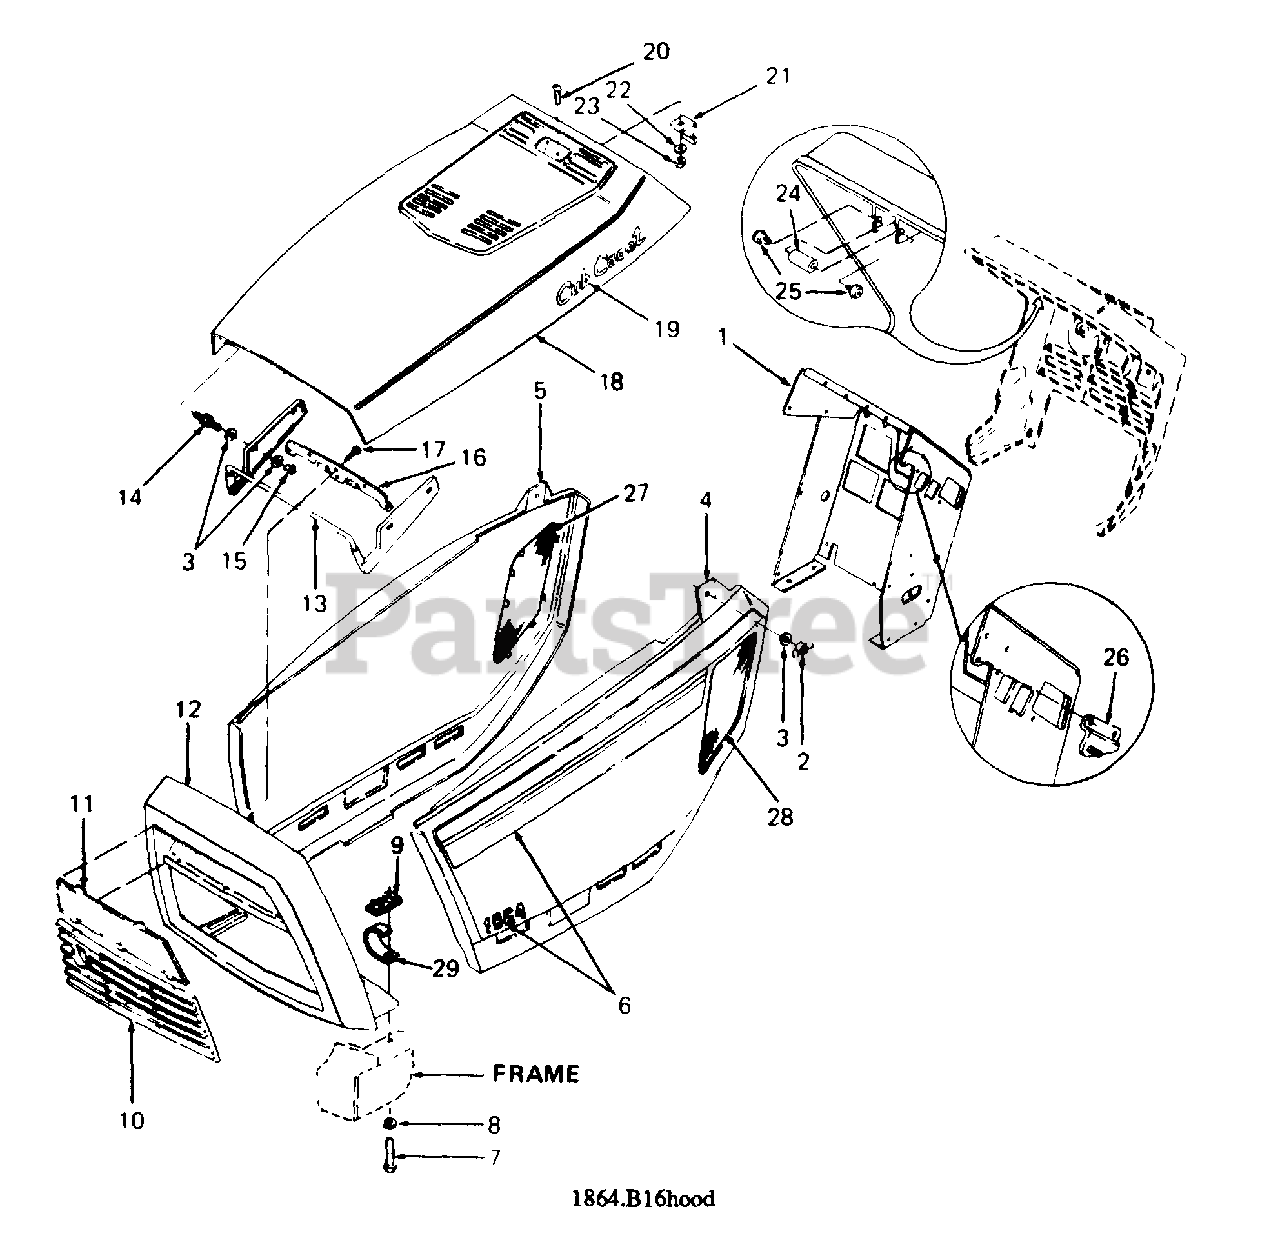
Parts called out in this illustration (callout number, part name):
3	Washer, Flat, .251 x .62 x .052 Thk
4	Panel, LH Side
5	Panel, RH Side
6	Graphics Kit, LH Side Panel
7	Screw, Hex Cap, 5/16-18 x 1.0 Lg GR5
8	Washer, Lock, 5/16
9	Retainer, Grille Housing
10	Grille, Insert
11	Grille, Lens
12	Grille Hsg
15	Nut, Hex Patch Lock, 1/4-20
18	Hood
19	Graphic, Cub Cadet Script w/Studs
20	Screw, Truss Hd, #8-32 x .38 Lg
21	Clip, Hood Latch
22	Washer, Flat, .16 x .38 x .045 Thk
23	Nut, Hex Keps, #8-32
24	Pin, Latch
25	Screw, Phillips Hd Truss Mach, 1/4-20 x .50 Lg
